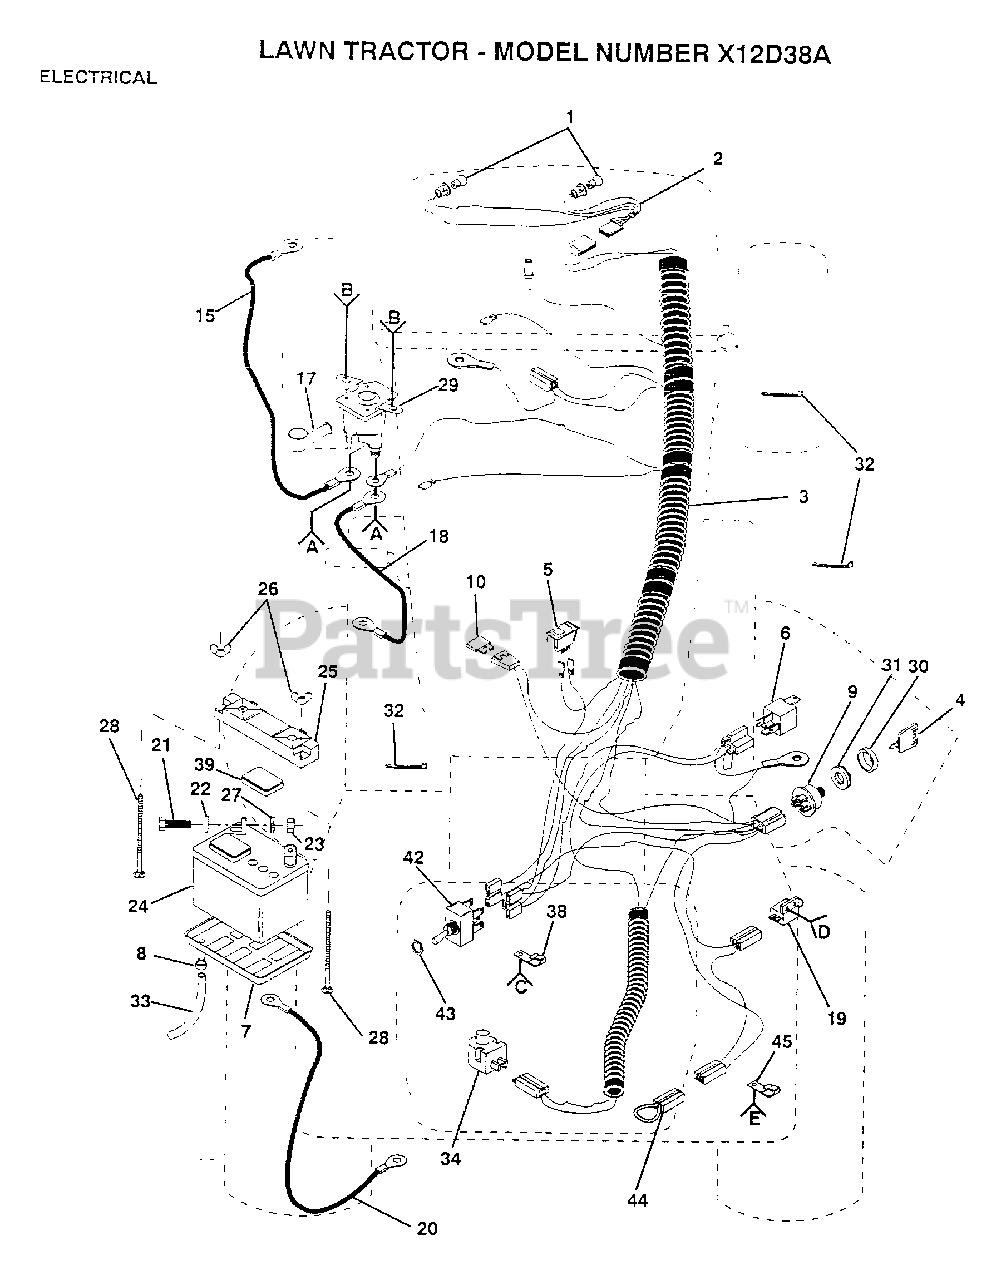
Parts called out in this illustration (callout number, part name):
2	HARNESS T
3	"HARNESS,IGNITION"
4	KEY
5	SWITCH LT
6	RELAY ASSY T
7	"TRAY T, BATTERY"
8	HOSE CLAMP T
10	FUSE HYT
15	CABLE ASM.
18	STARTER CABLE GT
19	SWITCH INTERLOCKT
20	CABLE T
21	BOLT LT
22	WASHER
27	LOCKWASHER
28	BOLT
32	WIRE TIE
34	SWITCH SEAT
39	"CAP,BATTERY "
45	CLIP, WIRE
